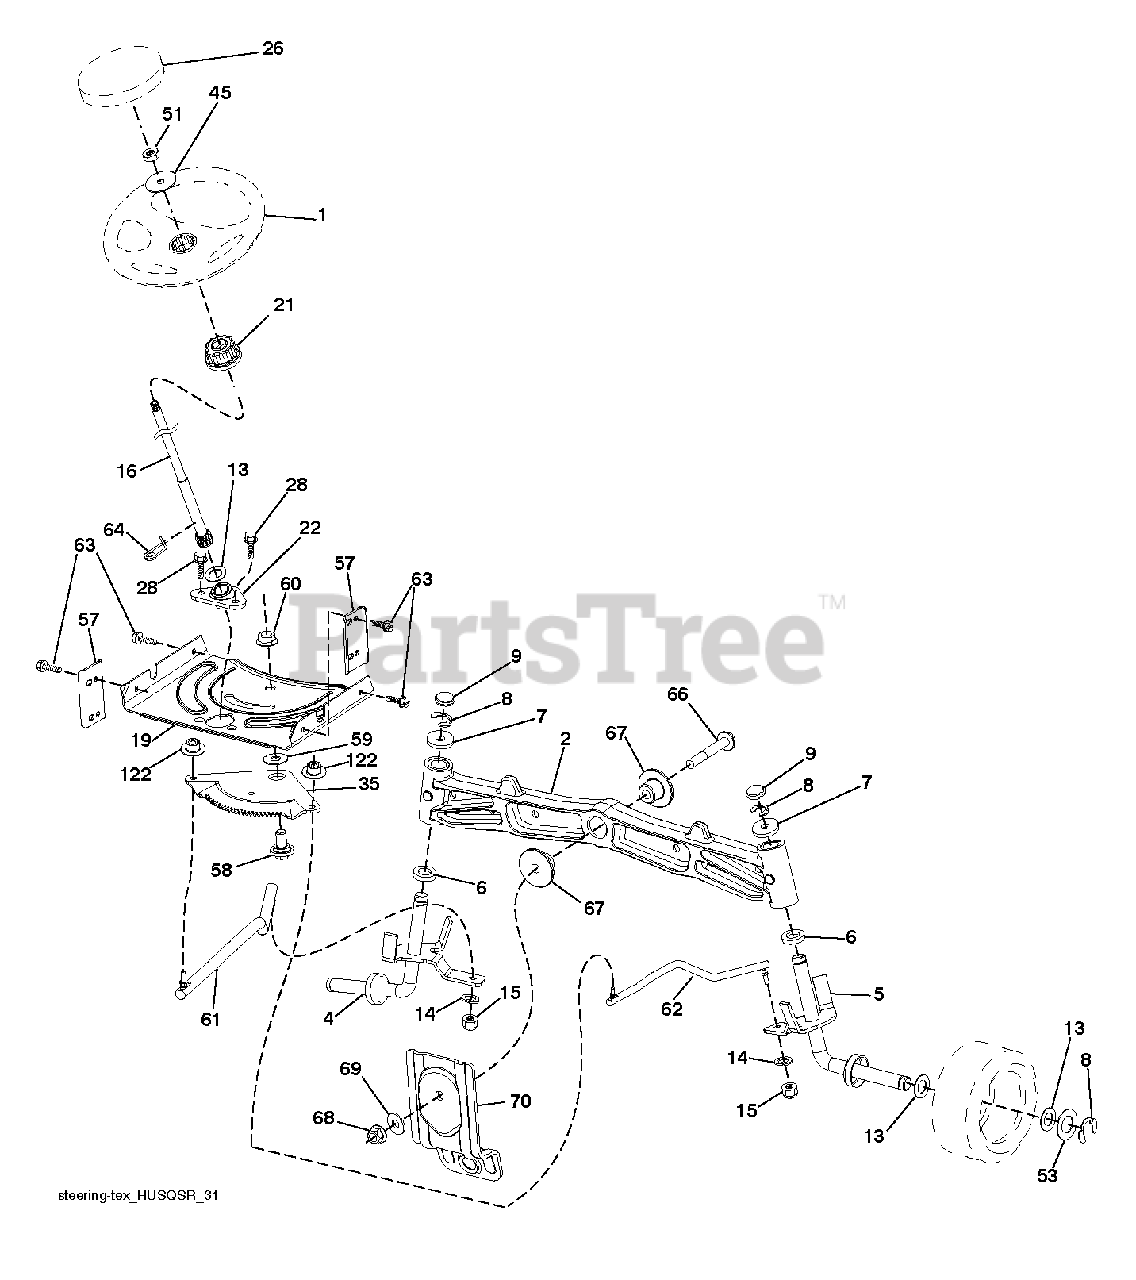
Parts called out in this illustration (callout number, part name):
1	WHEEL.STEER.HUSQ.SR.498.OVMLD
2	AXLE.CAST.IRON
4	SPINDLE.WELDED.LH.15"TEX
5	SPINDLE.WELDED.RH.15"T
6	THRUST WASHER
9	CAP.SPINDLE.BLACK
14	WASHER, LOCK 3/8
15	NUT CROWNLOCK 3/8-24
16	SHAFT, STEERING
19	PLATE.STEER.DDL.NLT/NG
21	ADAPTER, WHEEL STNG..
22	STEERING.SUPT.LOWER.
26	INSERT.CAP.WHL.STRG.HUSQ.PREM
28	SCREW, 3/8-16X3/4
35	GEAR.SECTOR.PLATE.DDL.
45	WASHER 9/16"ID, 2 3/8"OD
51	NUT.HEX.1/2-20
53	WASHER.HARDENED
57	BRACKET.UPSTOP.TEX
58	BOLT.SHOULDER.SECTOR.P
59	WASHER.THURST.SECTOR.S
60	NUT FLANGE LOCK 5/8-11
61	DRAGLINK.LH.BALLSTUD.D
62	DRAGLINK.RH.BALLSTUD.D
63	SCREW
64	RETAINER.CLIP.SPRING.S
66	BOLT HEX FGHD 7/16-14 X 3 SERR
67	BUSHING.PM.FRONT AXLE
68	NUT.LOCK.FLANGE.7/16
69	WASHER.1.5X.505X.118
70	BRKT.DECK.SUSPENSION.F
122	CAP.GEAR.SECTOR.TEX
